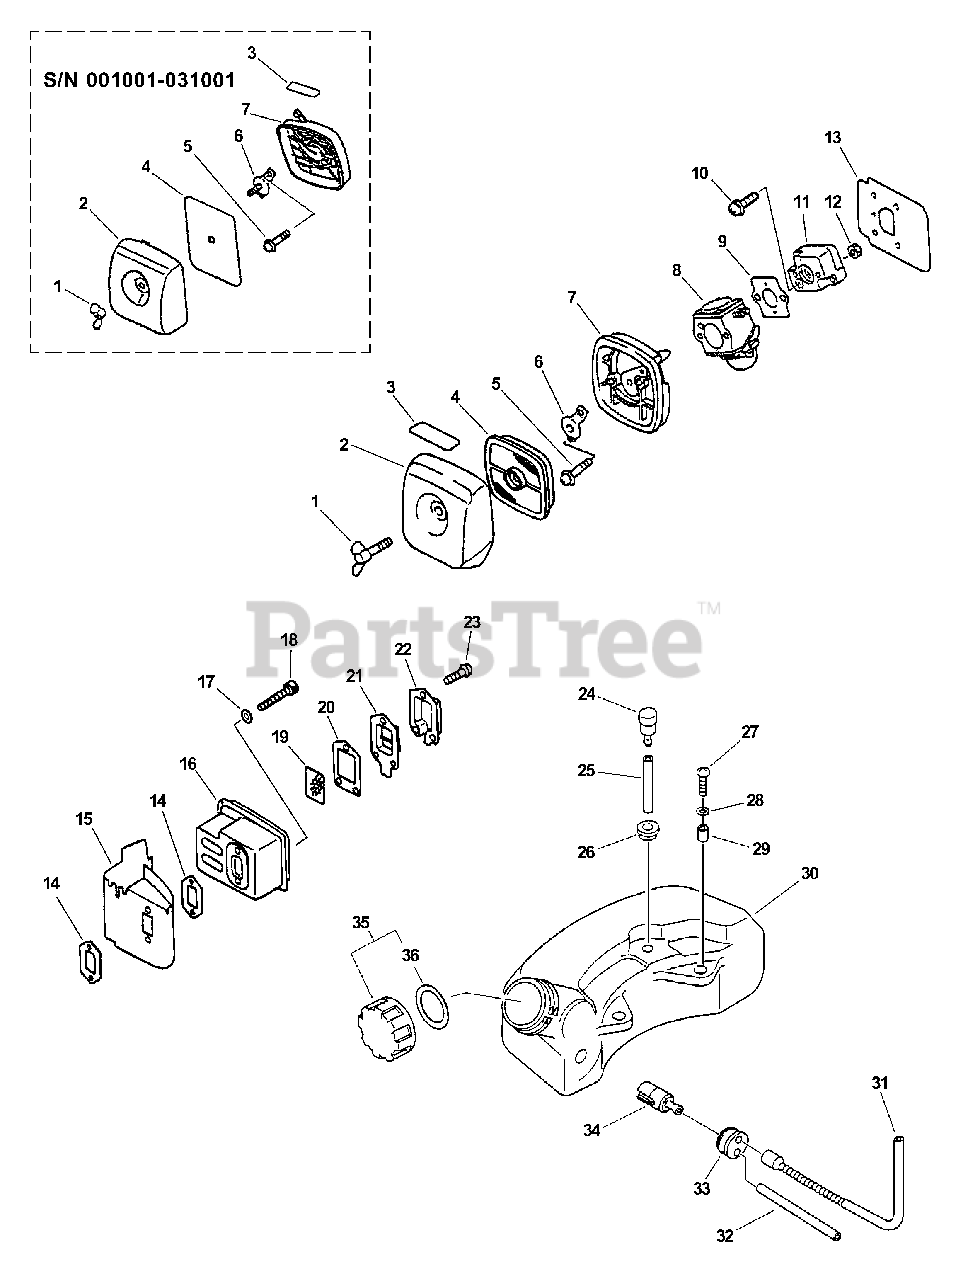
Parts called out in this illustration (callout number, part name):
1	WINGNUT - 6
1	THUMBSCREW
2	COVER, AIR FILTER
3	LABEL - CHOKE
4	FILTER, AIR
4	FILTER, AIR - SINGLE LAYER
5	SCREW - 5X65
6	PLATE, PREVENT
7	AIR FILTER CASE ASSY
8	CARBURETOR C1U-K31A
9	GASKET, INTAKE
10	SCREW - 5X20
11	INSULATOR, INTAKE
13	SHIELD, INTAKE
14	GASKET, EXHAUST
15	COVER, EXHAUST
17	WASHER - 5
18	SCREW - 5X55
19	SCREEN, SPARK ARRESTOR
20	GASKET, EXHAUST
21	GASKET, EXHAUST - INNER
22	GUIDE, EXHAUST - OUTER
23	SCREW - 4X10
24	VENT, FUEL TANK
25	PIPE - 3X6X35 -- BLACK
26	GROMMET
27	SCREW - 5X16
28	WASHER - 5
30	TANK, FUEL
31	PIPE, FUEL - CORRUGATED
32	PIPE - 3X6X110 -- CLEAR
33	GROMMET
34	FILTER, FUEL
35	CAP ASSY
36	GASKET, CAP
